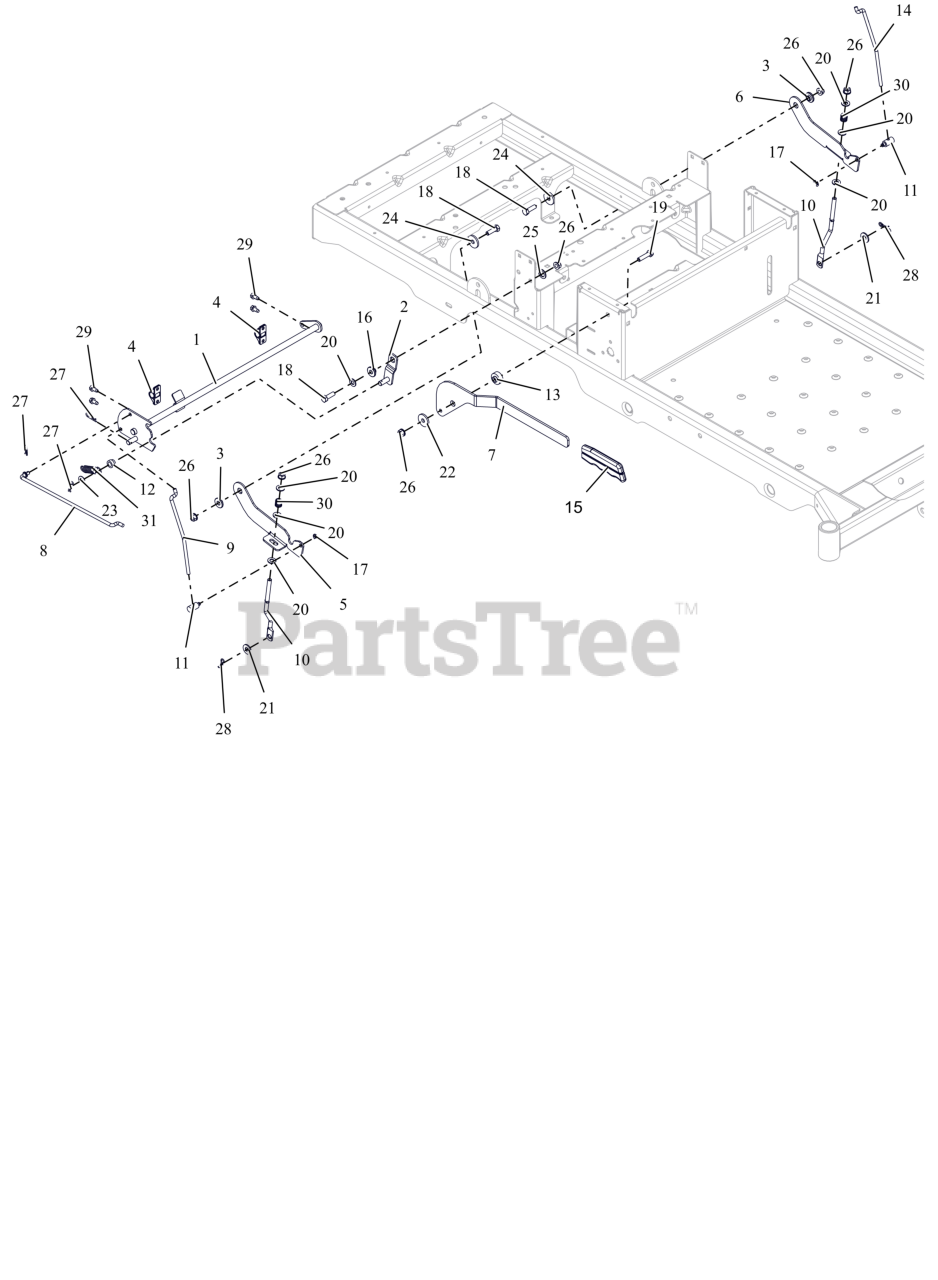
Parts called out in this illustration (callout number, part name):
1	WELDMENT, BRAKE SHAFT
2	WELDMENT,DETENT ARM
3	BSHG, FLG .325X.499X.26X.88
4	BUSHING-.50 CLAMP BLOCK MOLDED
5	LATCH,RH NETURAL
6	LATCH,LH NETURAL
7	HANDLE, PARKING BRAKE
8	LINK, BRAKE HANDLE
9	LINK, NEUTRAL RH
10	LINK, BRAKE COG
11	TRUNION, 1/4-20
13	SPCR,BRAKE .32X.49X.192X1.00
14	LINK, NEUTRAL LH
15	GRIP, PARKING (GRAY)
16	BSHG-FLG .32X.500X.344X.880
17	RG-RTNG-EXT .250X.025
18	BLT,HEX .31-18X1.00 G5 ZCC
19	BLT, HEX .31-18X1.25 G5 ZCC
20	WSHR,FLT .344X.688X.065 ZCC
21	WSHR,FLT .375X.875X.083 ZCC
22	WSHR, FLT .340X1.125X.135 ZCC
23	WSHR, FLT .385X.745X.030 ZCC
24	WSHR, FLT .340X1.125X.135 ZCC
25	WSHR, FLT .520X.827X.062 ZCC
26	NUT,LK-CTR-FLG .31-18 GF ZCC
27	PIN, HAIR #213 .08X1.19 ZCC
28	PIN, BOWTIE #72 ZCC
29	SCR-TAP .25-20X.50 HWH ZCC
30	SPRING, COMPRESSION
31	SG-TENS .072X.565X1.87
